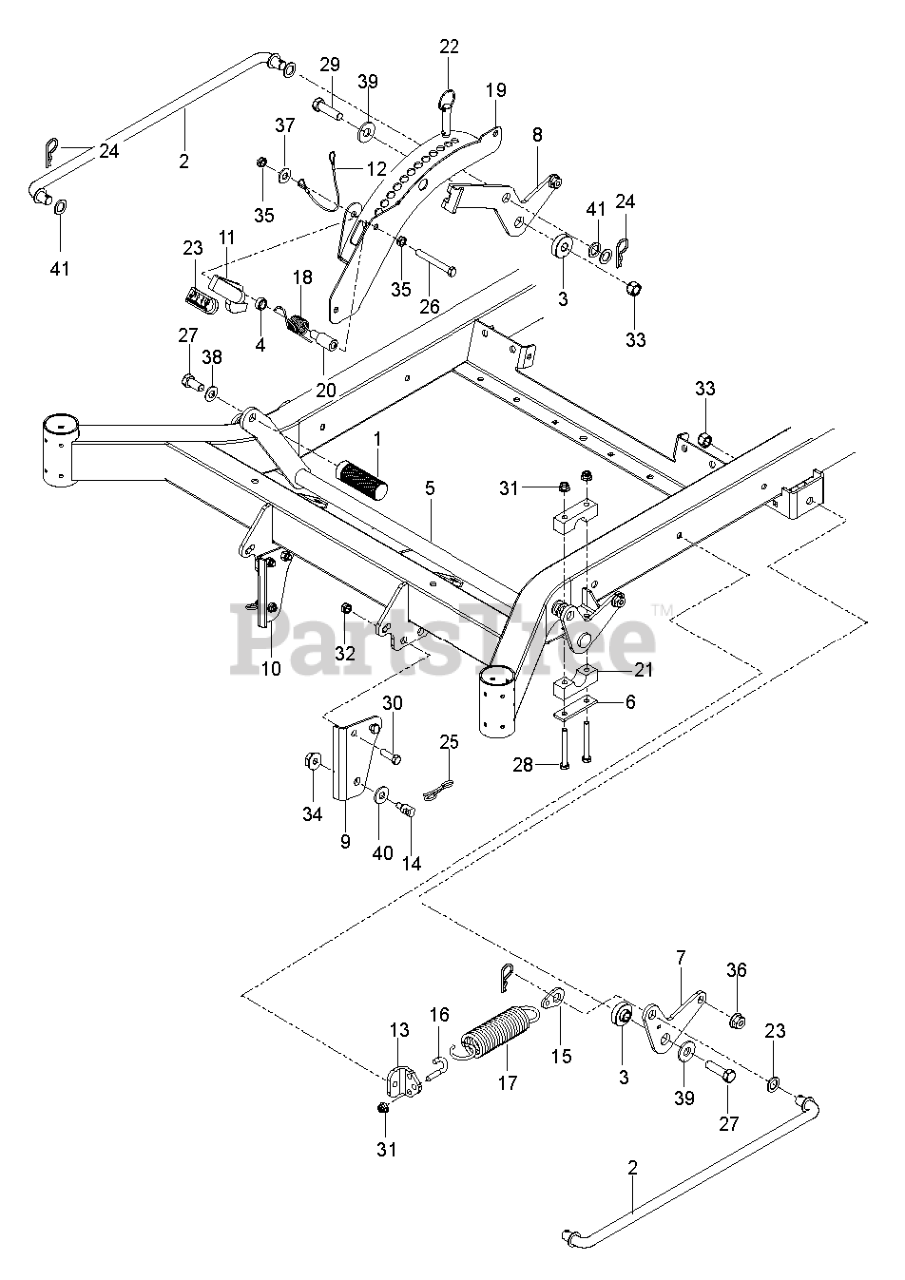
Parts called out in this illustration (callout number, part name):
1	PEDAL, DECK HEIGHT
2	CROSS LINK
3	SPACER.IDLER.METAL.POWDER
4	SPACER, .3
5	LIFT.PNT.MZ.DECK.WELD.E-DIP
6	REINFORCEMENT.PLATEX431
7	BELLCRANK, RR, LIFT
8	BELLCRANK REAR.RT BLACK X431
9	BRACKET.PNT.SUSP.CHAS.FR.LH.OR
10	BRACKET.PNT.SUSP.CHAS.FR.RH.OR
11	LATCH, TRANSPORT
14	STUD.FASTNER.W/ANTI-ROTATE
18	SPRING, TORSION
19	HEIGHT, ADJUST, DECK
20	PIVOT, LATCH, TRANSPORT
21	PILLOW BLOCK
22	PIN, 1/2 X 1 1/2, DETENT RING
23	GRIP, TRANSPORT-RELEASE
24	PIN, COTTER 1 3/4
25	PIN.COTTER.7/16.BOW TI.
26	BOLT.HEX.FIN.3/8-16 X 3.GR5
27	HHCS 1/2-13 X 1
29	HCS 1/2-13 X 1 3/4 GR 8
30	HCS 3/8-16X1.GRD.5.ZD
31	5/16-18 NYLOC FLANGE NUT
32	NUT 3/8-16 NYLOC
33	NUT.LK.W/WSH.1/2.
34	NUT LOCK HEX FLANGE 5/16-18
35	NUT HEX 3/8-16 NYLON, THIN
36	NUT LOCK FLG 3/8-16 UNC
37	RP WASHER 3/8 FLAT
38	CONTACT BELLSPR 1/2
39	WASH USS FLAT 1/2
40	WASHER.CLEAR.ZINC
